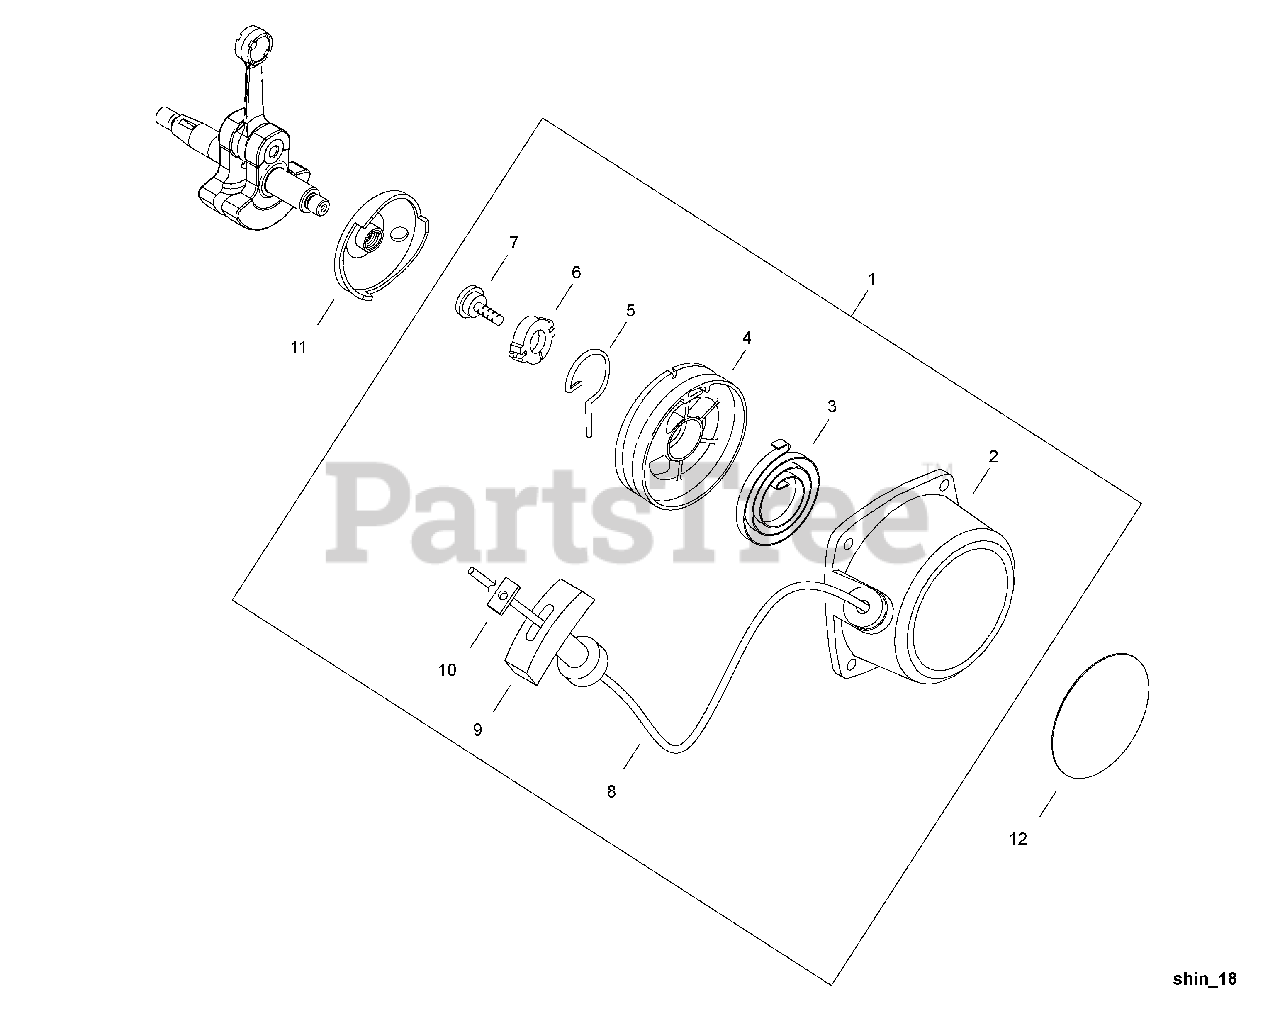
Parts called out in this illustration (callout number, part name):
1	STARTER ASSY, RECOIL
2	CASE, RECOIL STARTER
3	SPRING, RECOIL
4	REEL, ROPE
5	ARM, SWING
6	WASHER 5
7	SCREW 5
8	ROPE, STARTER
9	GRIP, STARTER
10	RETAINER, ROPE
11	PULLEY, STARTER
12	LABEL, T282 ID
